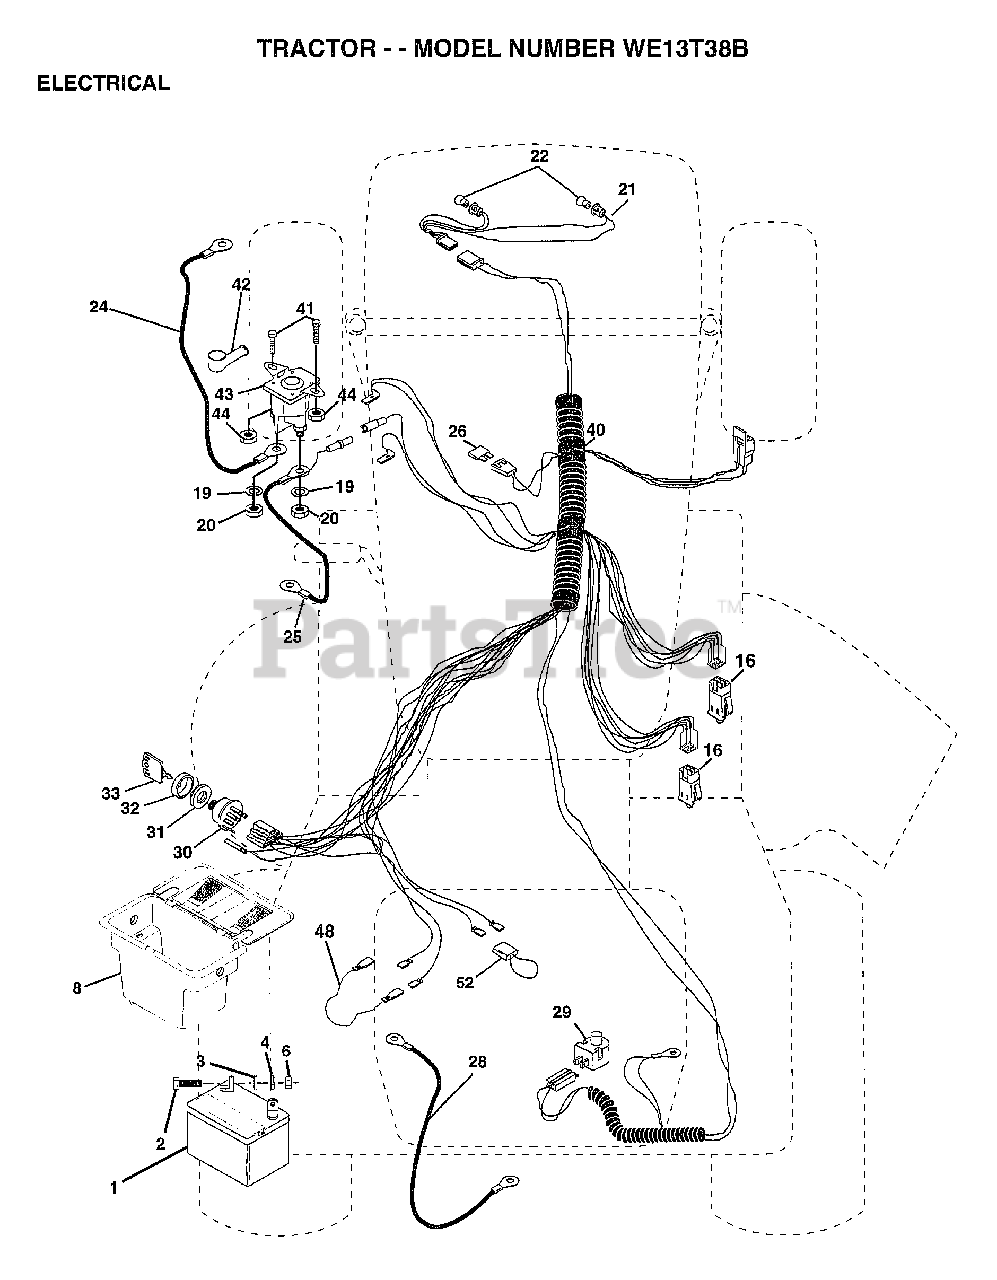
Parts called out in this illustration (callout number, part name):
2	BOLT LT
3	WASHER
4	LOCKWASHER
8	"CASE,BATTERY.MECH"
16	SWITCH INTERLOCK
20	NUT
21	"HARNESS,LIGHT SOC"
22	HEADLAMP BULB
24	CABLE ASM.
25	CABLE.BTRY.6GA.RD
26	FUSE HYT
28	CABLE T
29	SWITCH SEAT
30	SWITCH IGN 4POS
31	NUT IGNITION
32	COVER KEY SWITCH
33	KEY
40	HARNESS-IGNITION
41	BOLT HXHD FIN
44	NUT HXKEP 1/4X20
48	ADAPTER AMMETER
52	PROTECTION LOOP
